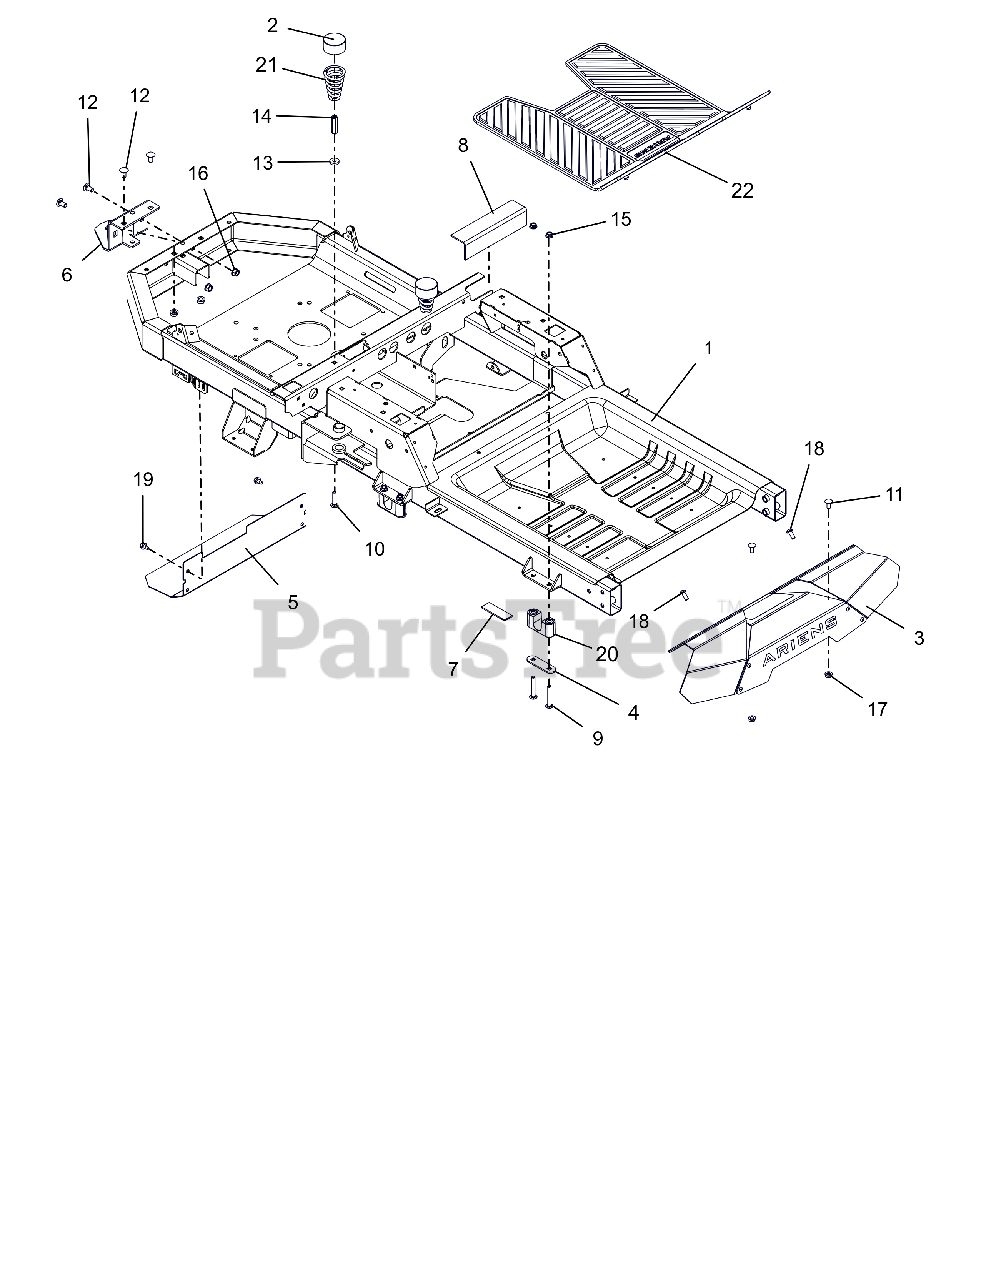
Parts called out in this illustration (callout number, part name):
1	KIT, IKON-X/XL FRAME (2016)
2	HUB CAP
3	KIT, IKON FOOT REST W/DECAL
4	PLATE, BEARING SUPPORT
5	HEAT, SHIELD
6	BRKT, HITCH TONGUE
7	PAD,RBR 1.0"X3.0" W/ADHESIVE
8	PAD, RUBBER-TANK
9	BLT-RDHDSQSHNK .31-18X2.25 YWZ
10	@BLT-RDHDSQNK .31-18X1.50 G5YZ
11	@BLT-RDHDSQNK .31-18X.75 G5YZ
12	@BLT-RDHDSQNK .38-16X.75 G5YZ
13	WSHR-FL-STL .328X.87X.179 YWZC
14	NUT, COUPLING 5/16-18 X 1 3/4
15	@NUT-LK-CTR-FLG .31-18 YZ GR F
16	@NUT-LK-TOP-FLG .38-16 YWZC
17	@NUT-LK-TOP-FLG .31-18 YWZC
18	SCR-RDHDSKTAP .31-18 X .75
19	@SCR-TAP .31-18X.50 HWH TR YWZ
20	BSHG, DECK LIFT PIVOT
21	SPRING, SEAT
22	FLOOR MAT, RUBBER - ARIENS
